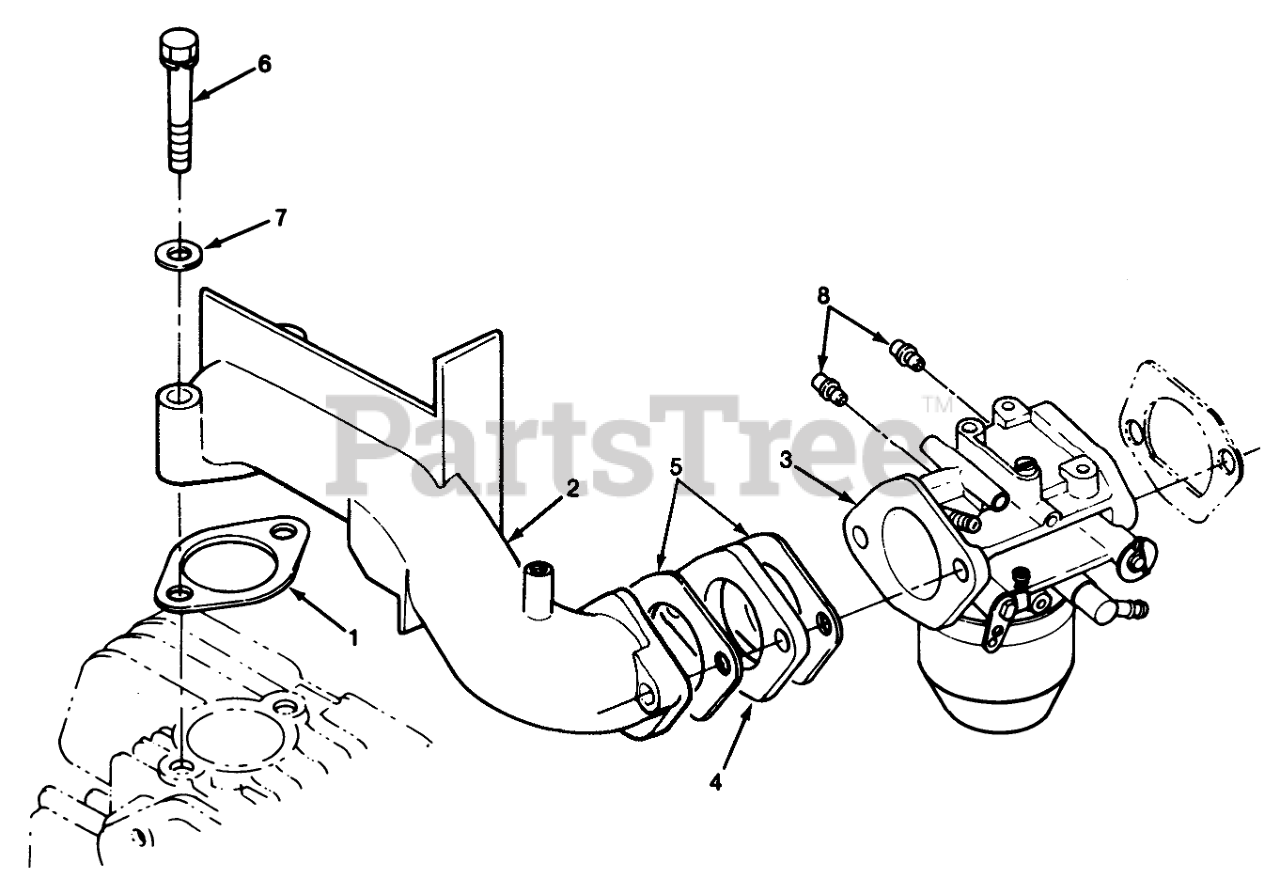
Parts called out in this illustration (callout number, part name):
1	Gasket
2	ELBOW-INTAKE
3	CARBURETOR
4	INSULATOR
5	Gasket
6	HHCS-M8 X 50MM
7	Nut-M8
8	Clip
